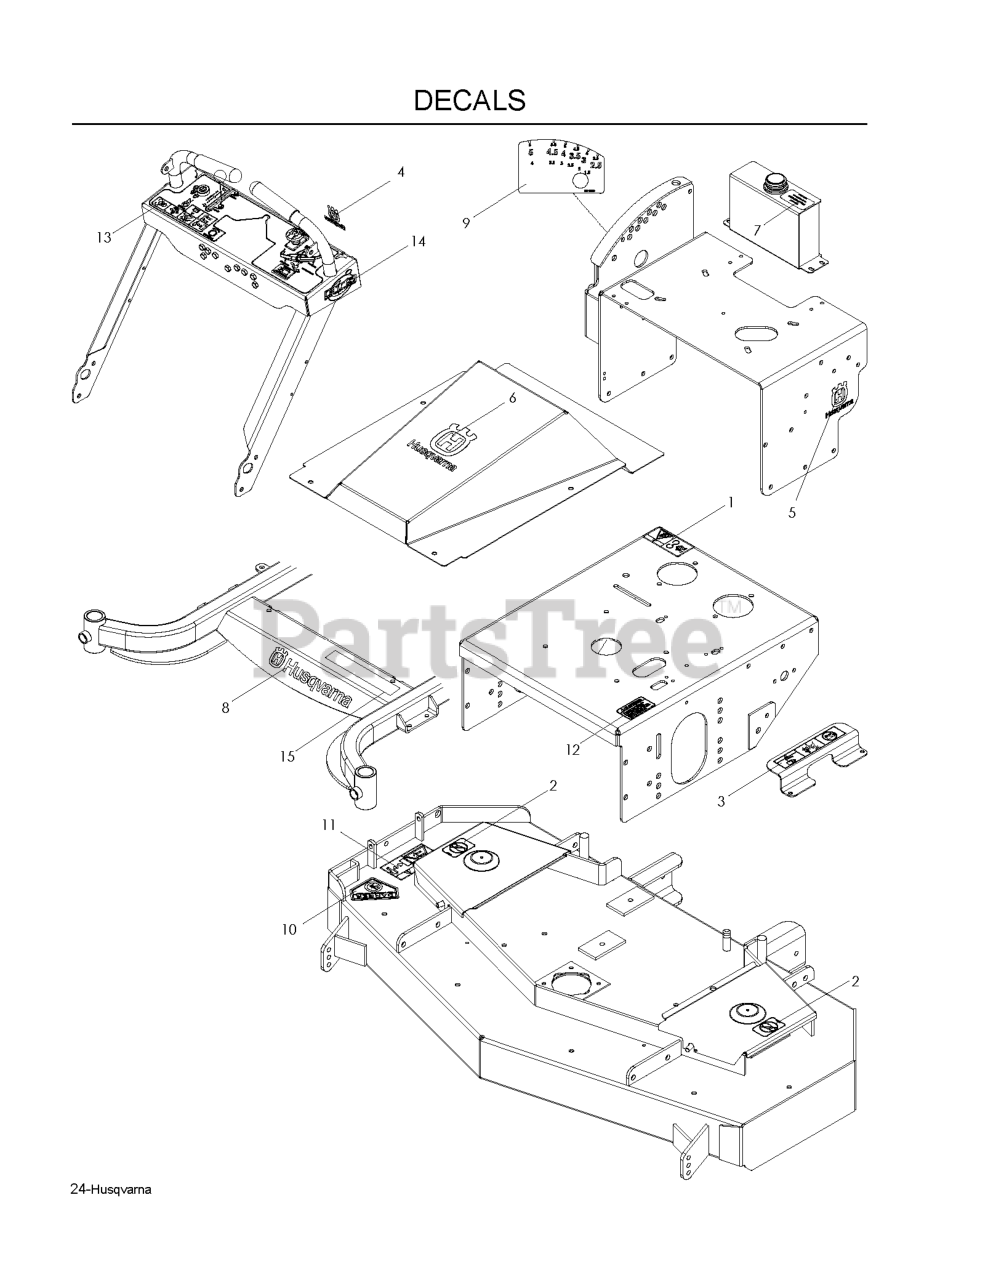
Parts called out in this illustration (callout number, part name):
1	DECAL, BELT DRIVE
2	DECAL, NO STEP
3	EURO DECAL-BATTERY WARNIN6
4	DECAL CROWN H 2-1/4 BLUE
5	DECAL, CROWN H 3-1/8 BLUE
6	DECAL, CROWN H BLUE
7	DECAL, OIL TANK
8	DECAL, HUSQ 9-1/4 BLUE
9	DECAL, HEIGHT ADJ
10	DECAL, CPSC
11	DECAL, EURO SEVERING
12	DECAL, PROP. 65
13	CONSOLE DECAL
14	DECAL, ETS
15	DECAL, WHF5219
